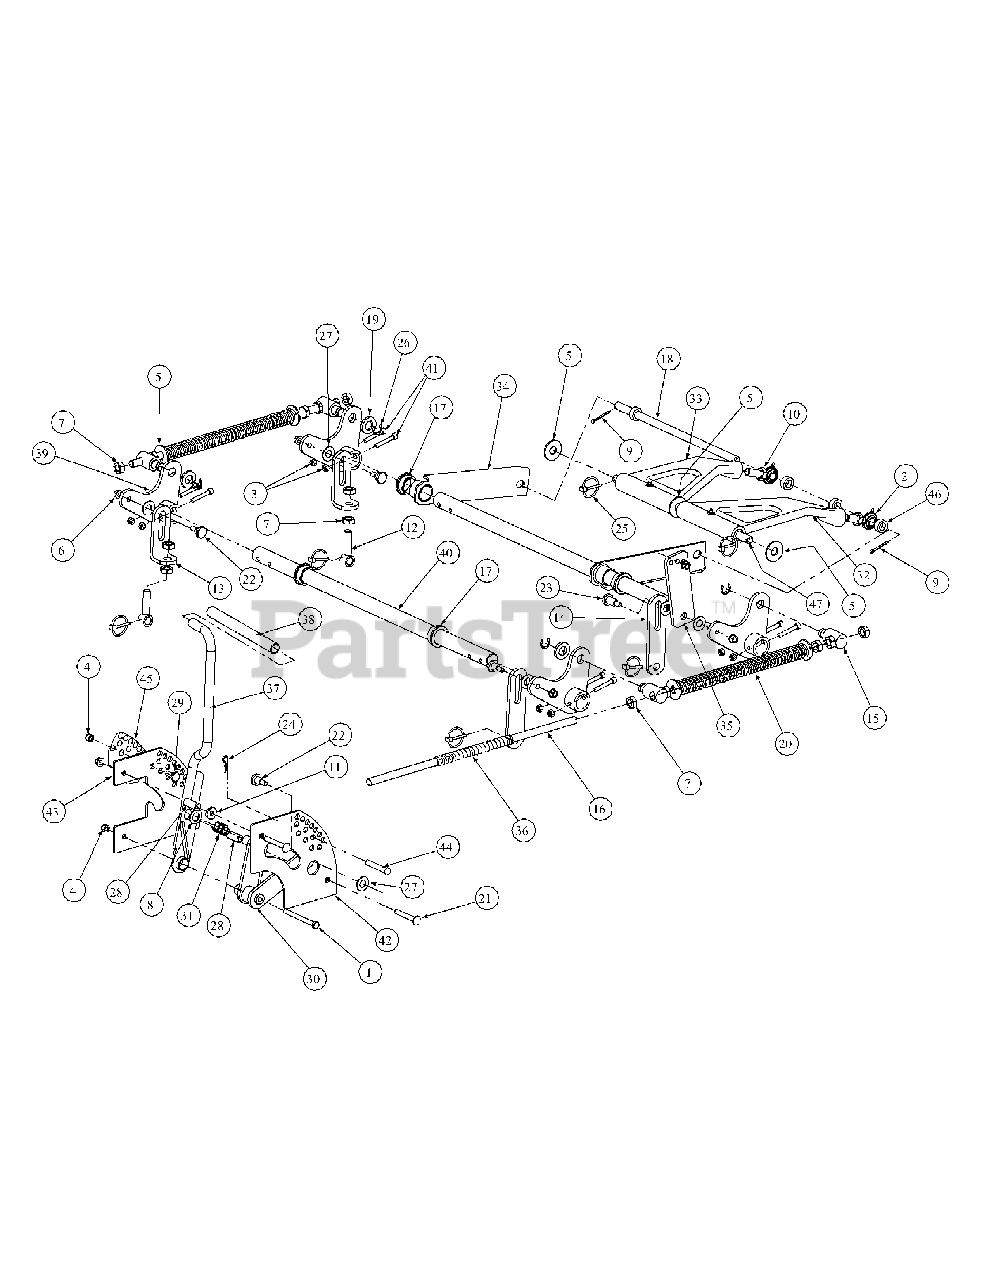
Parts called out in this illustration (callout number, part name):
1	Hex Cap Screw, 3/8-16, 3.75
2	Rod End, Male
3	Nut, 5/16-18, Nylock
4	Nylock Insert Lock Nut, 3/8-16
5	Flat Washer, 5/8
6	Hex Nut, Flange Lock, 3/8-16
7	Jam Nut, 5/8-11
8	Flat Washer, .06, .776, 1.25
9	Cotter Pin, 3/16 x 1-1
10	Jam Nut, 5/8-18
11	Idler Washer
12	Eye Bolt, 5/8ID
13	Eye Bolt Mount Link, 5/8 ID
14	Deck Link
15	Ferule Lift
16	Lift Connector Rod
17	Hex Flange Bearing, 1.25 ID
18	Front Lift Link, Rod Mount
19	Spacer, .812 ID x .268 Lg.
20	Lift Compression Spring
21	Carriage Bolt, 3/8-16, 2.75
22	Shoulder Screw, 0.625 OD x .437 Lg.
23	Shoulder Screw, 0.625 OD x .830 Lg.
24	Cotter Pin, .148 x 3.00
25	Linch Pin, 3/16 Dia.
26	E Clip, 3/4 Dia.
27	Nylon Flat Washer, 5/8
28	Spacer, .39 ID x .63 OD x 1.442
29	Shoulder Screw, .50 OD x 0.27
30	Lift Pivot Assembly
31	Lift Handle Spring
32	Bearing Lift Brace Assembly, Right Hand
33	Bearing Lift Brace Assembly, Left Hand
34	Front Frame Strut Assembly
35	Lift Link Adjustment
36	Hose, 5/8 ID 13/16 OD, 8" LG
37	Lift Handle Assembly
38	Lift Handle Grip
39	Bellecrank Weldment Assembly
40	Deck Lift Shaft
41	Socket Head Cap Screw, 5/16-18 x 2
42	Outer Lift Index Plate
43	Inner Lift Index Plate
44	Clevis Pin, .438 Dia. x 2.625 Lg.
45	Decal Height Indicator
46	Spacer, .630 ID x 1.06 OD x .440
47	Lift Link Rod
